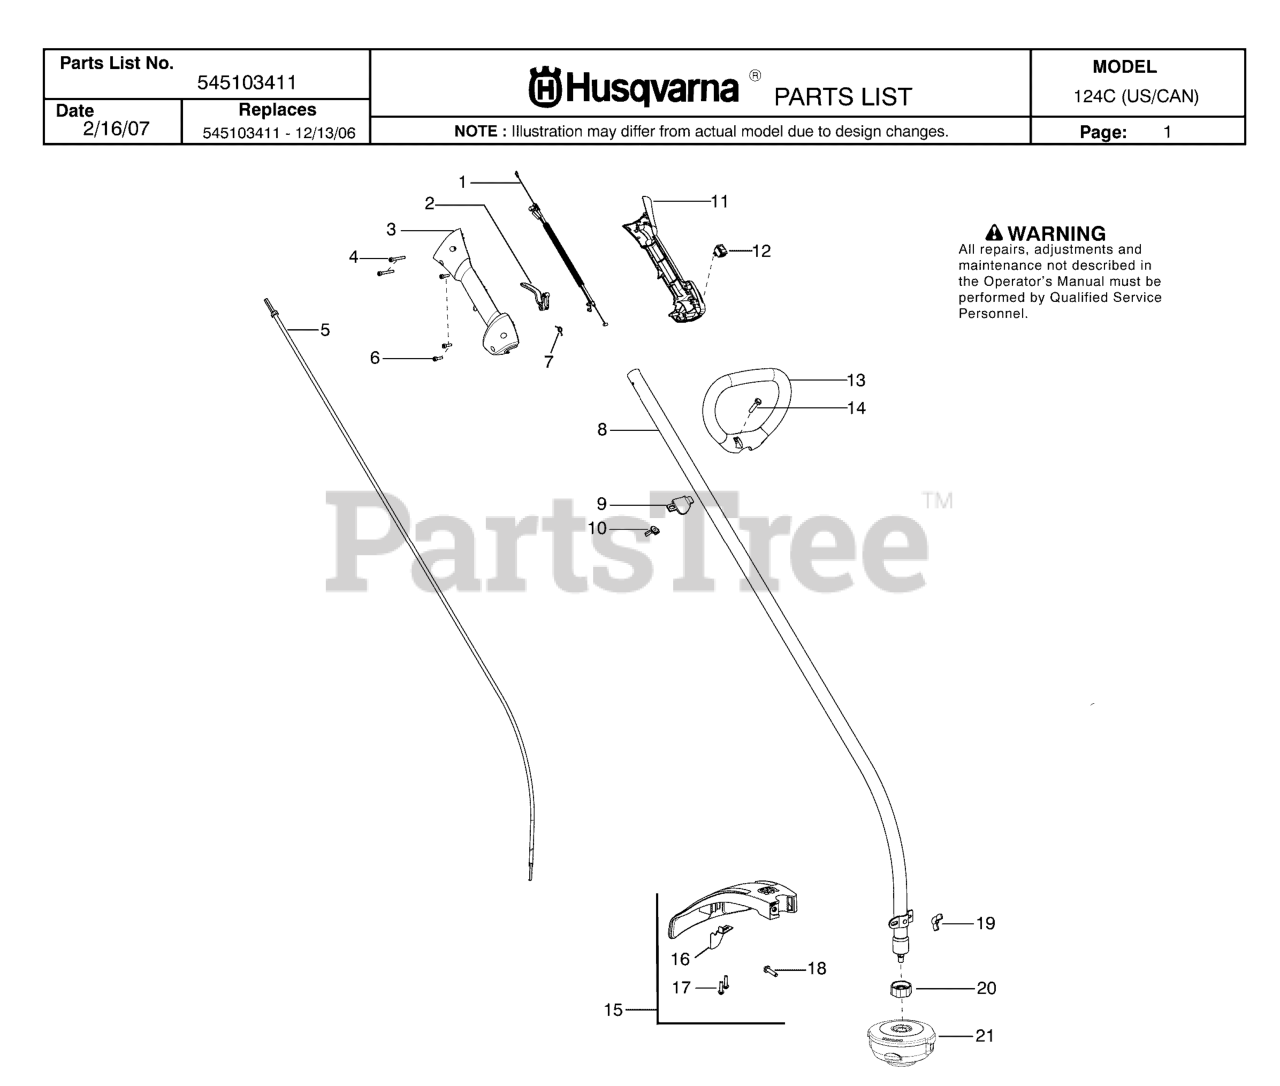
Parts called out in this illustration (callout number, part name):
1	Assy-Cable/Wire Harness
2	TRIGGER THROTTLE
3	HOUSING-THROTTLE (RH)
5	Flexshaft
6	SCREW M4 X 1.75 PT 16MM
7	SPRING TRIGGER
8	KIT DRIVESHAFT
9	CLAMP ASSIST HANDLE
10	WINGNUT, TYPE 2
11	HSG THROTTLE LH
12	KIT SWITCH
13	HANDLE ASSIST
14	BOLT, TYPE 2
15	TRIMMER GUARD 128C
18	BOLT, TYPE 2
19	WINGNUT, TYPE 2
21	T25 TRIMMER HEAD 3/8 RH
